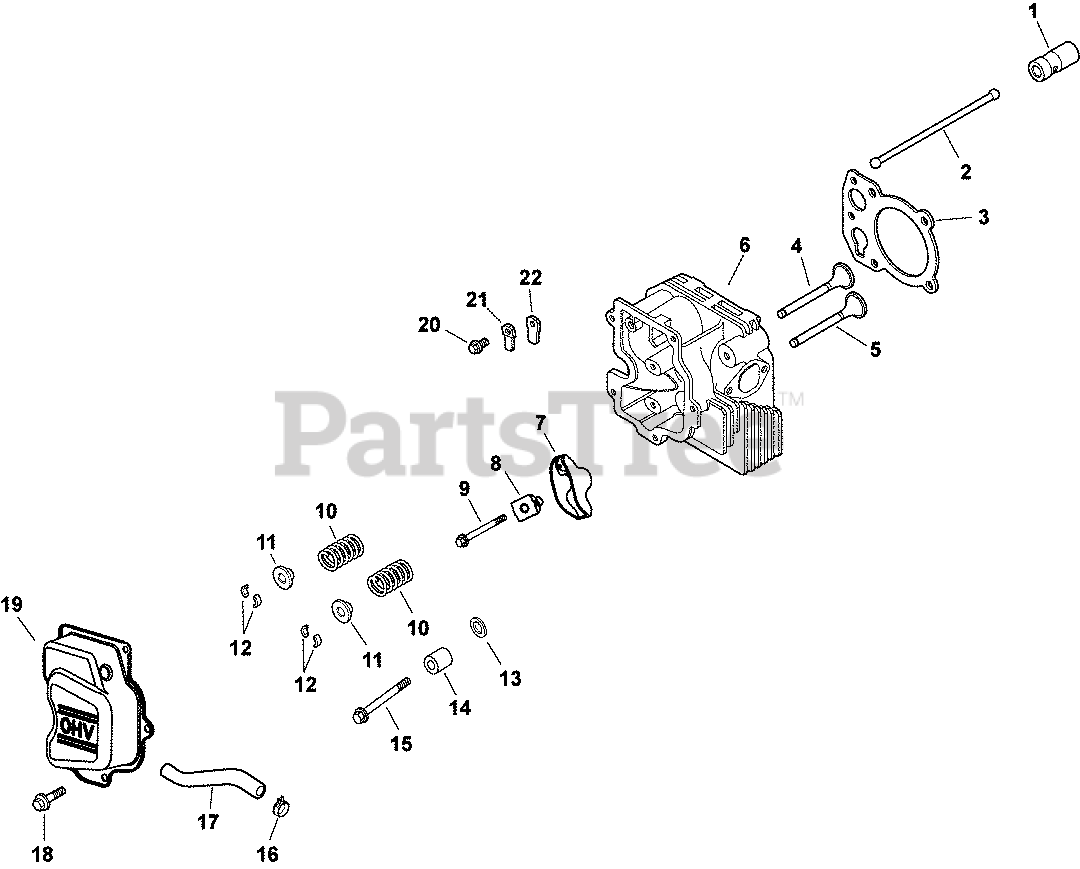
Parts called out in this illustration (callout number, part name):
1	LIFTER, HYDRAULIC VALVE-USE 25 351 10-S
2	ROD, PUSH
3	GASKET, CYLINDER HEAD
4	VALVE, INTAKE
5	VALVE, EXHAUST
6	HEAD ASSEMBLY, CYLINDER
7	ARM, ROCKER
8	PIVOT, ROCKER ARM
9	SCREW, FLG M6X1.0X34
10	SPRING, VALVE
11	RETAINER, VALVE SPRING - USE 25 173 28-S
12	KIT, RETAINER
13	WASHER, FLAT 13/32"
14	SPACER, HEAD BOLT EXHAUST PORT
15	SCREW, CYLINDER HEAD (M10 X 80)
16	CLAMP, HOSE (KM)-USE 25 237 31-S
17	HOSE
18	SCREW,FLG THD FRM M6X1.0X16-(#25086397S)
19	COVER, ROCKER
20	SCREW, FLG THD FRM M5X.8X10
21	RETAINER, REED
22	REED, BREATHER
1232630-S	HOSE, BREATHER
